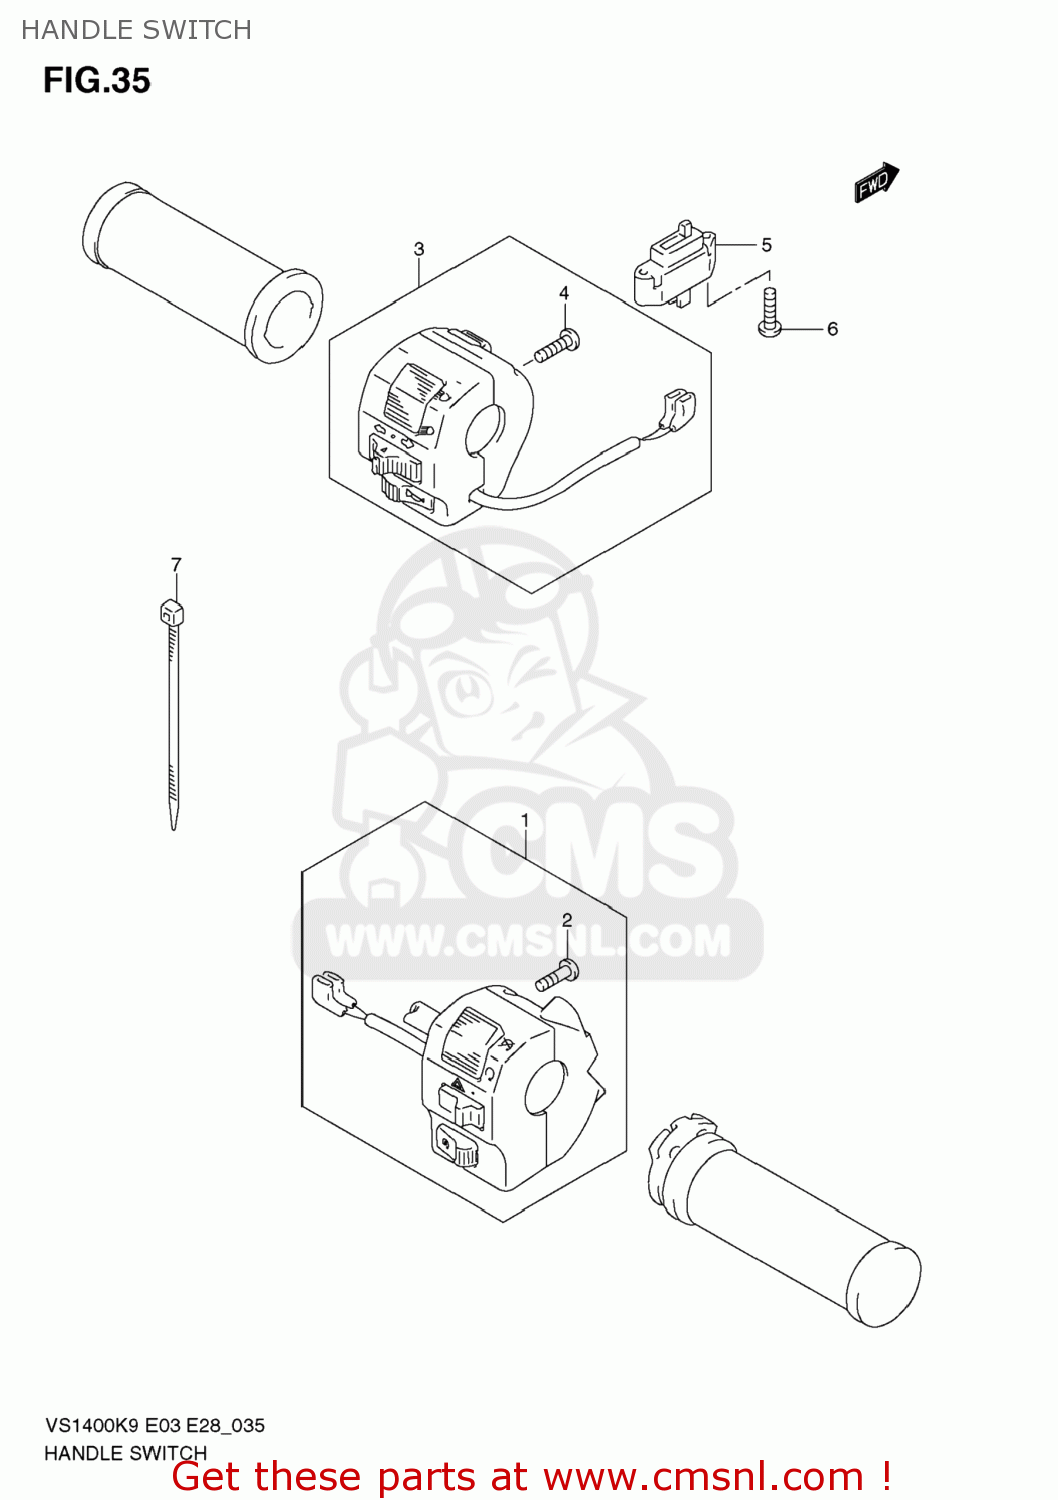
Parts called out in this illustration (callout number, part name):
1	SWITCH ASSY,HANDLE,R
2	SCREW
3	SWITCH ASSY,HANDLE,L
4	SCREW
5	SWITCH ASSY,CLUTCH
6	SCREW
7	CLAMP(L:145)
